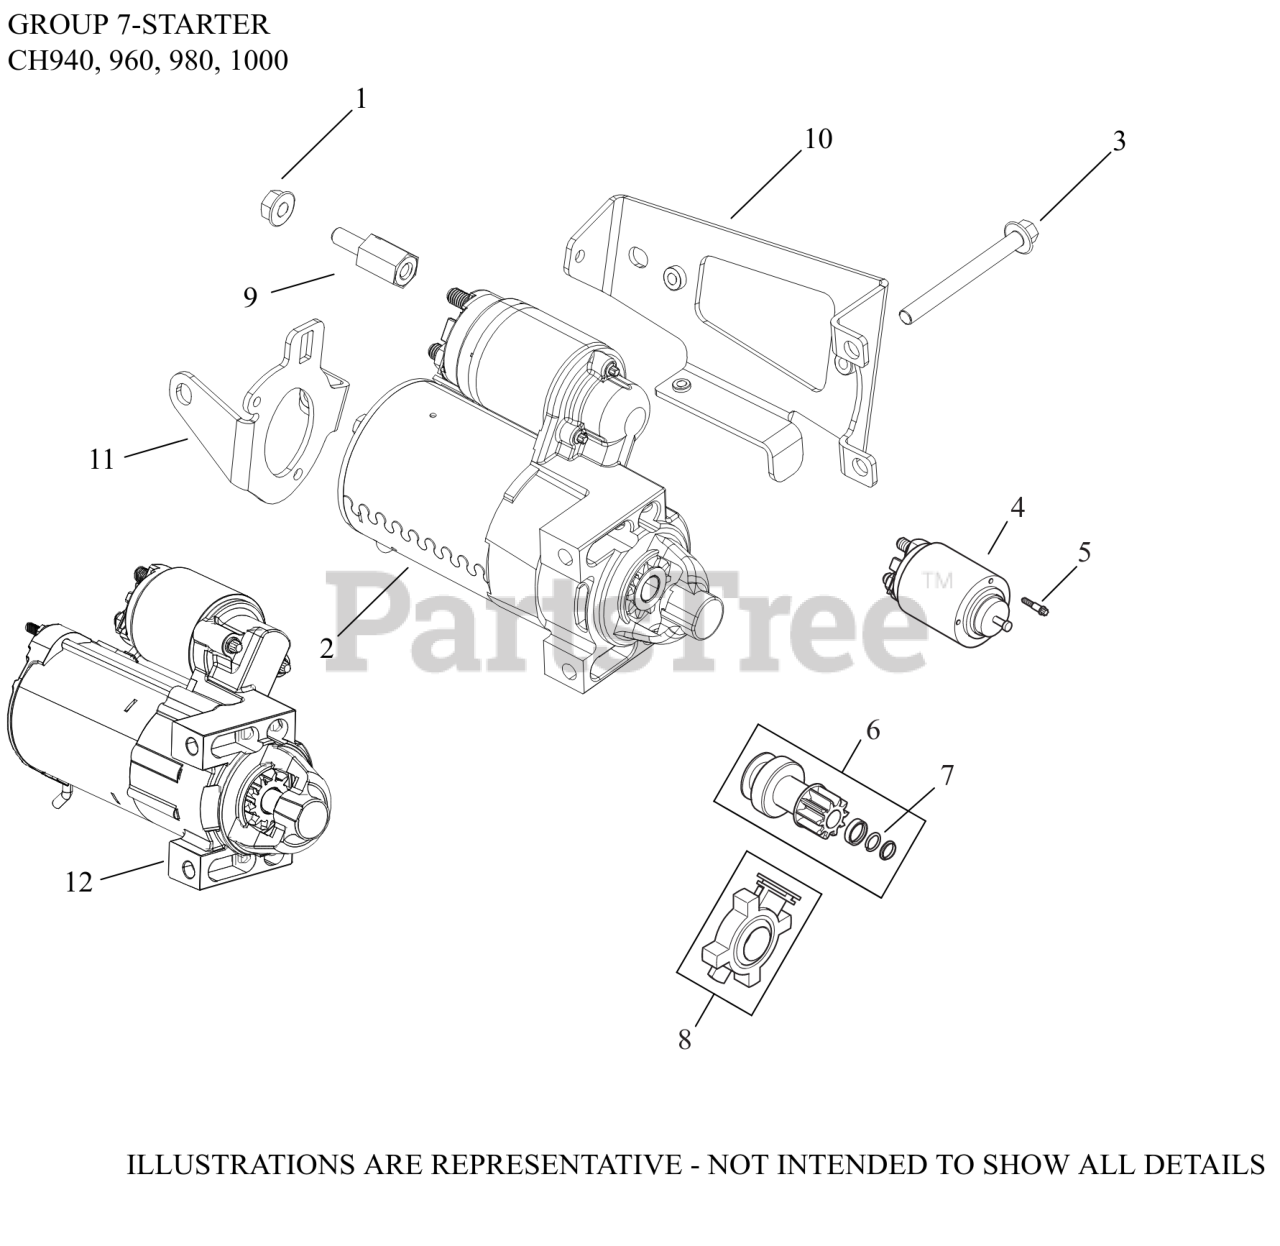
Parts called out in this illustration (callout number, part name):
1	NUT, FLG M8X1.25
2	STARTER, SOLENOID SHIFT-(#2509824S)
3	SCREW, FLG M8X1.25X80
